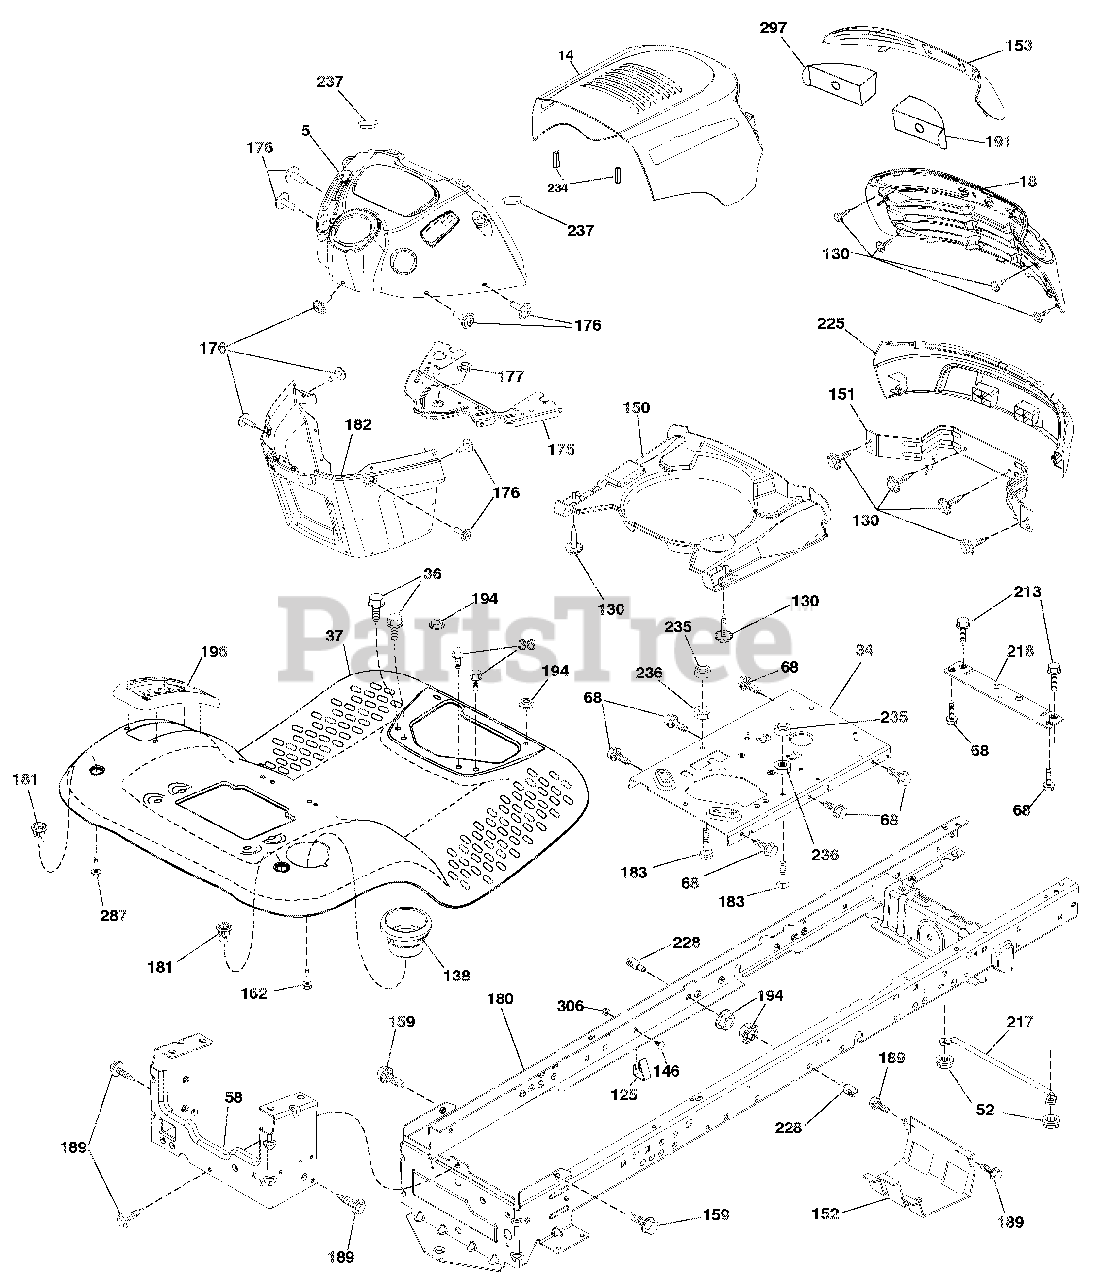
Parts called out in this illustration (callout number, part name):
18	GRILLE
34	PLATE.ENGINE.WELDED.CHASSIS
36	SCREW.5/16-18X3/4.SMGML.TAP/R
37	FENDER TLT W/CPH W/FW 422
52	Nut, Hex, Crownlock 5/16-18
58	DRAWBAR.UPPER.2PC.SML.FENDER
68	SCREW.THDROL.5/16-18 X 1/2TYTT
125	CLIP.FUEL.LINE
138	CUPHOLDER TL TEX 428
150	AIR DUCT.INTAKE.B&S
151	Bracket Pivot
152	SHIELD.BROWNING.W/TEX
153	LENS, ARIENS
159	SCREW.HEXWSH THDR3/8-16X3/4.BL
162	SCREW.HEX.WSH.HI-LO.1/4X1/2UNC
175	CROSSMEMBER.LT
176	SCREW.#10-24X5/8.RND.QUDRX.GIM
177	BUSHING.STEERING.LT
180	CHASS.WLDMT.TL.12GA/2PC.18/22"
181	BUSHING MNT FEND CRGO BLK TEX
182	DASH LOWER
183	BOLT.FIN.HEX.5/16-18 UNC X1-1/
189	SCREW.5/16-18X3/4.SMGML.TAP/BL
191	INSERT REFLECTIVE RH
194	Nut, Lock Hex Flange 5/16-18 u
196	CONSOLE ASM.DECKLFT.BL/RBT.TLT
213	Bolt, Hex Head 5/16-18 x 3/4
217	ROD.PIVOT.HOOD
218	X-PIECE.HOOD.STOP.NON/STEALTH
225	BUMPER
228	STUD.FASTNER.W/'D'ANTI-ROTATIO
234	BUMPER HOOD
235	SPACER.FENDER
236	NUT.CENTER LOCK.5/16-18 UNC
237	PLUG.MOUNT.CARGO
287	SCREW.HEX.WASHEAD.1/4-20 X 3/8
297	INSERT REFLECTIVE LH
306	Nut, Hex, Flangelock 3/8-16
